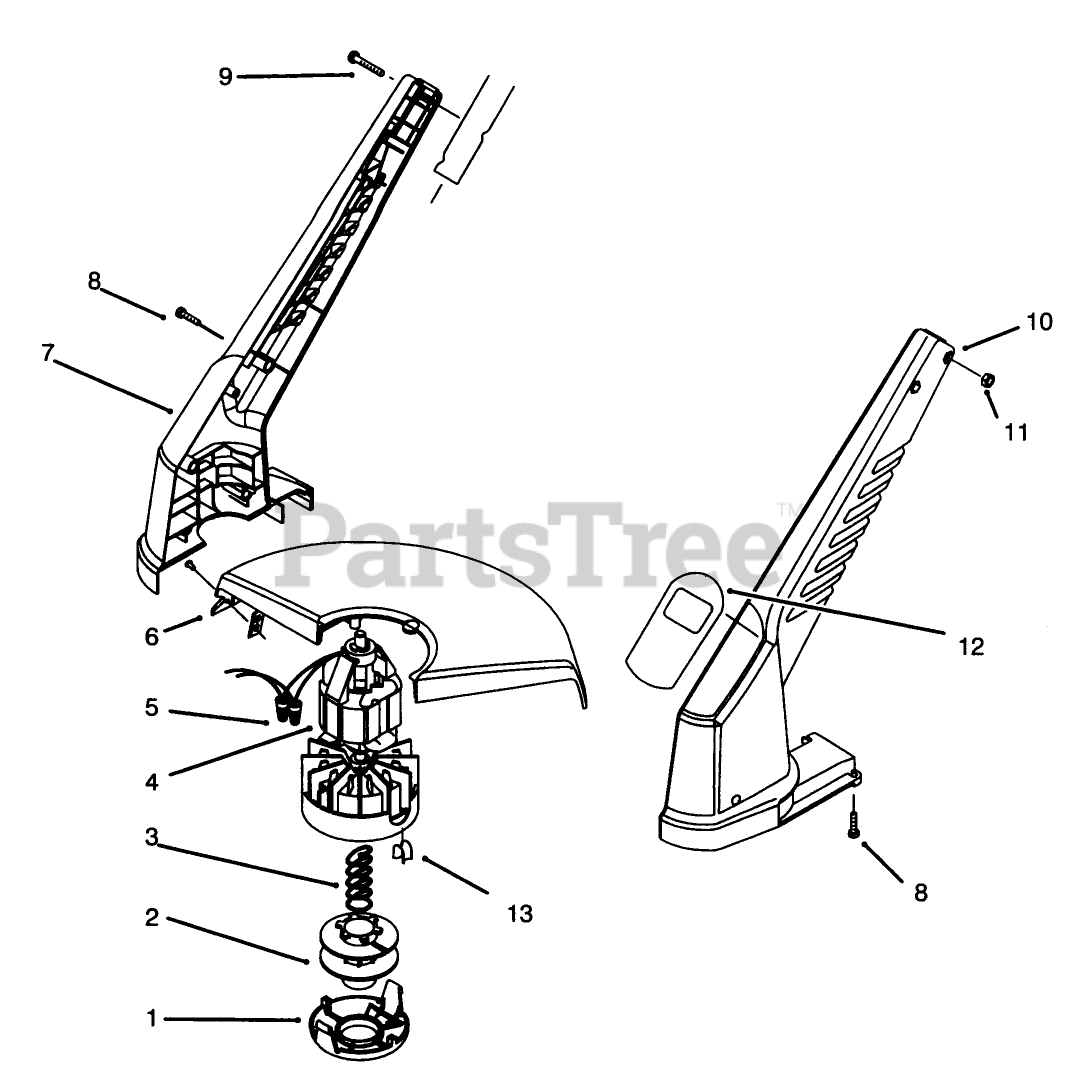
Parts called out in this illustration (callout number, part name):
2	SPOOL-LARGE
3	SPRING-COMPRESSION
4	Motor Assembly (Incl. Ref. #13)
5	CONNECTOR-NUT, WIRE
6	SHIELD ASM - SERVICE
7	RH HOUSING
8	Screw
9	SCREW-PPH
10	LH HOUSING
11	NUT-HEX
12	DECAL - 14" TRIMMER
13	EYELET
